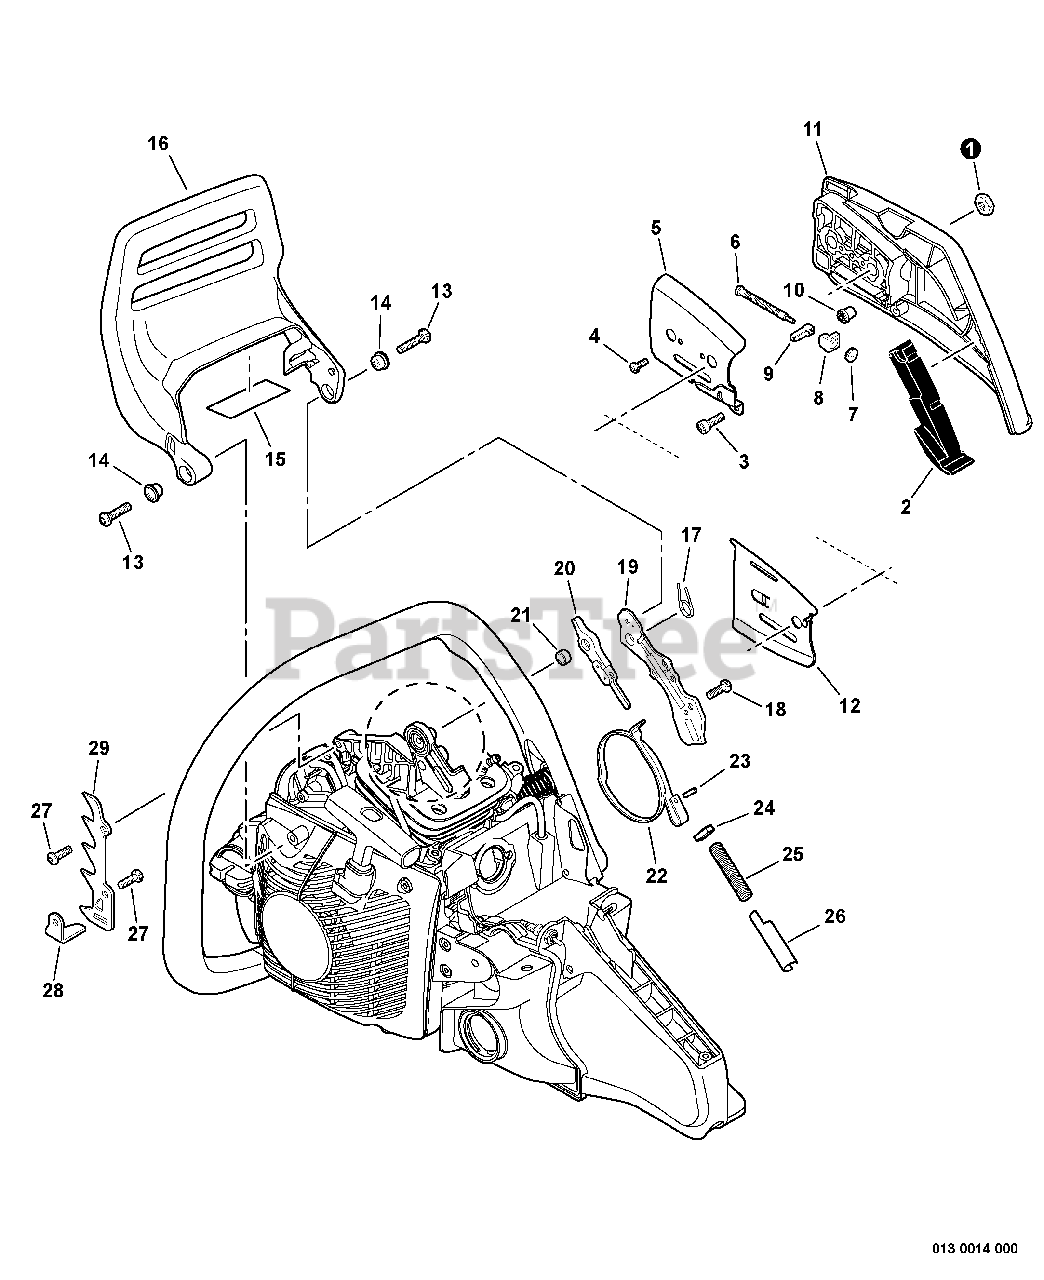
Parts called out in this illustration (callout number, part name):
2	CUSHION
3	BOLT, TORX 4×12
4	SCREW 3×6
5	PLATE, GUIDE - OUTER
6	SCREW, CHAIN TENSION
7	GEAR, BEVEL
8	COLLAR 8
9	TENSIONER, CHAIN
10	GEAR, BEVEL
11	GUARD, SPROCKET
12	PLATE, GUIDE - INNER
13	BOLT, TORX 5×16
14	COLLAR 11.2×16.2×T0.6
15	SHIELD, HEAT 75×27×0.15
16	BRAKE, CHAIN
17	SPRING, TORSION
18	BOLT, TORX 5×16
19	COVER, BRAKE
20	CONNECTOR, BRAKE
21	SPACER 12×10×T: 1.0
22	BAND, BRAKE
25	SPRING, COMPRESSION Ø12×70.5
26	PLATE, SIDE
27	BOLT, TORX 5×16
28	CHAIN CATCHER
29	SPIKE, BUMPER
